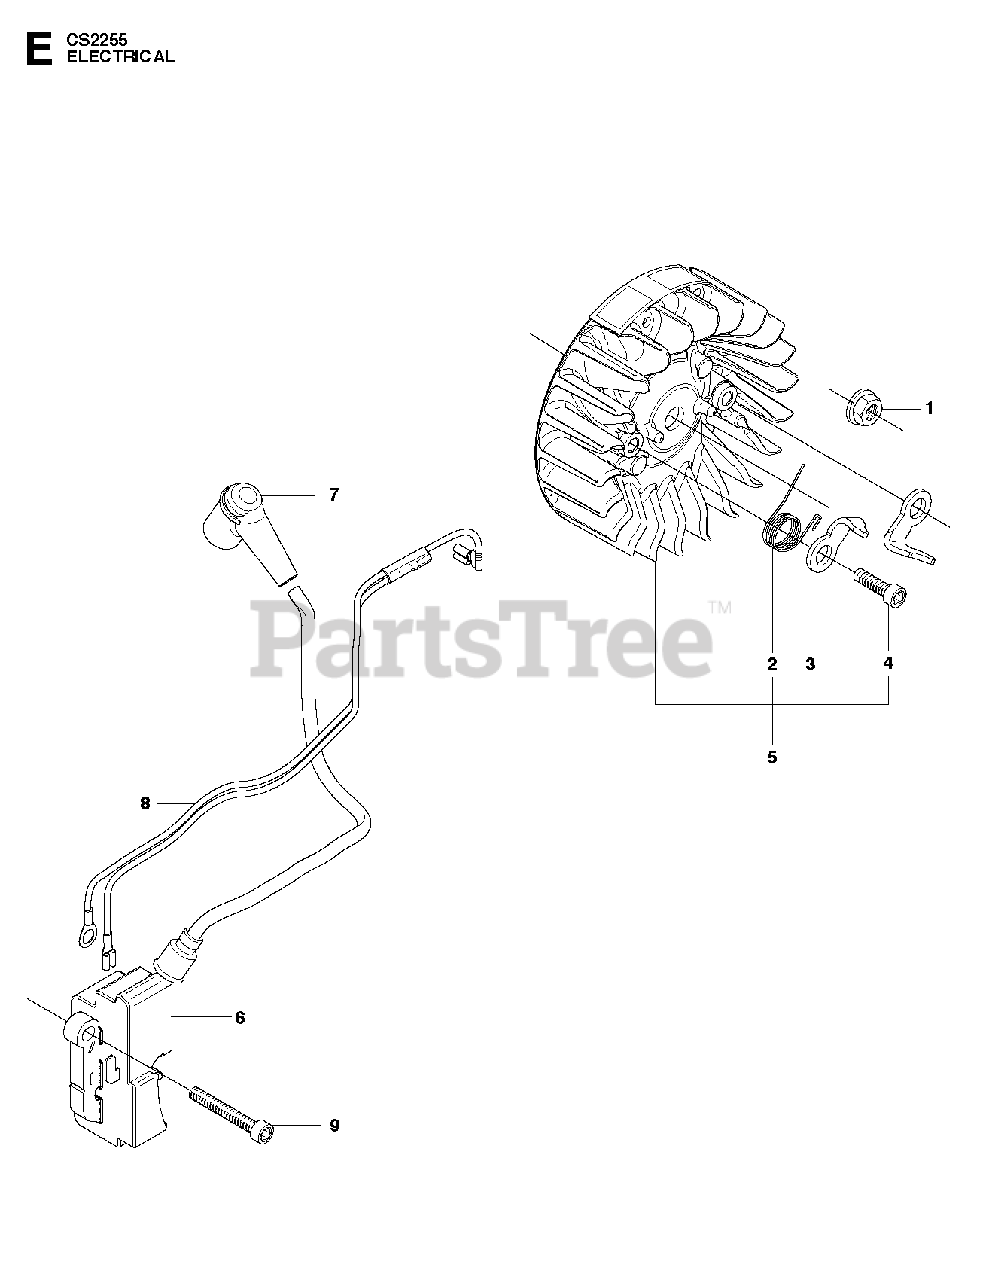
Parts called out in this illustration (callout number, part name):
1	NUT W/ WASHER
2	SPRING
3	PAWL
4	PIN, STARTER CATCH
6	IGNITION MODULE
7	SPARK PLUG CONN. KIT
8	CABLE ASSY
